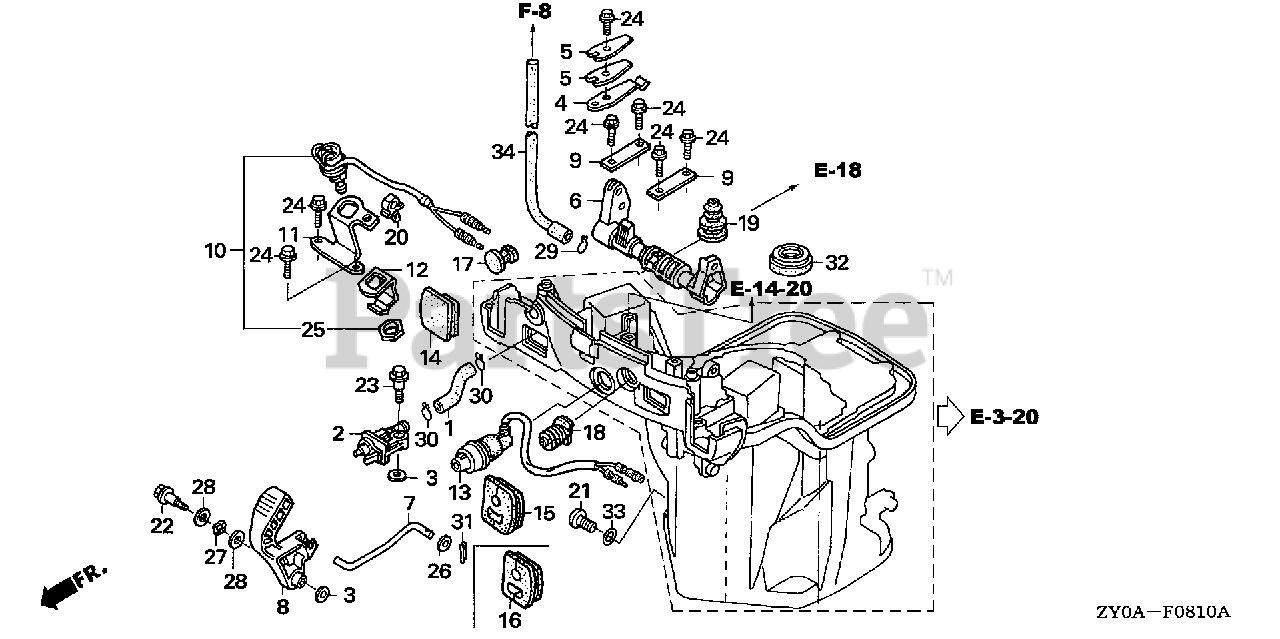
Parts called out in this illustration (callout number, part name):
1	TUBE A, FUEL
2	CONNECTOR ASSY., FUEL (B)
3	WASHER, PIVOT
4	SPRING, CLICK
5	SPRING, CLICK ASSIST
6	SHAFT, SHIFT
8	LEVER, SHIFT
9	PLATE, SHIFT SHAFT
13	LAMP ASSY., INDICATOR
14	GROMMET A, OIL CASE
15	GROMMET B, OIL CASE
18	GROMMET D, OIL CASE
19	GROMMET E, OIL CASE
21	BOLT, OIL CHECK
22	BOLT, REVERSE LOCK
23	BOLT, SPECIAL (6X22) (CT200)
24	BOLT, FLANGE (5X12) (CT200)
26	WASHER, PLAIN (5MM)
27	WASHER, WAVE (10MM)
28	WASHER, PLAIN (9MM)
29	CLIP, TUBE (B10)
30	CLIP, TUBE (B12)
31	PIN, SPLIT (2.0)
32	SEAL, WATER (15X28X6)
33	O-RING (5.5X1.5)
34	TUBE, WATER CHECK
